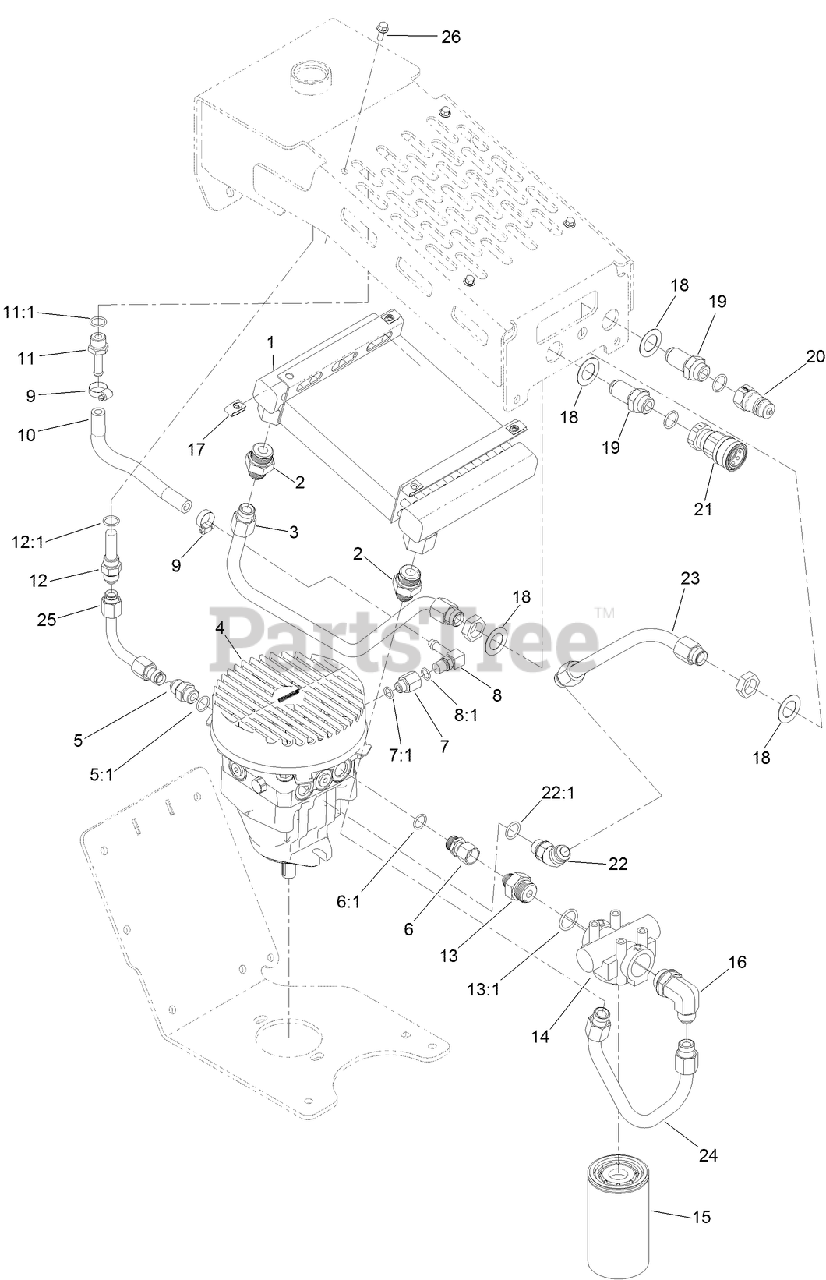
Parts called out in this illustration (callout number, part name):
1	COOLER-HYDRAULIC
2	FITTING-STRAIGHT
3	HYDRAULIC TUBE ASM
4	PUMP-HYDRO
5	FITTING-STRAIGHT
5:1	O-RING
6	ADAPTER
6:1	O-RING
7	FITTING-STRAIGHT
7:1	O-RING
8	FITTING-ELBOW, 90
8:1	O-RING
9	CLAMP-HOSE
10	HOSE-HYD
11	FITTING-STR
11:1	O-RING
12	FITTING-SCREEN
12:1	O-RING
13	FITTING-STRAIGHT
13:1	O-RING
14	FILTER HEAD ASM
15	FILTER-OIL,TRANSMISSION
16	ADAPTOR-ELBOW
18	WASHER-THRUST
19	FITTING-BULKHEAD ASM
20	DISCONNECT-QUICK , MALE
21	DISCONNECT-QUICK, FEMALE
22	FITTING-ELBOW
22:1	O-RING
23	TUBE, RETURN
24	HYDRAULIC TUBE ASM
25	TUBE, SUCTION
26	SCREW-HHF
